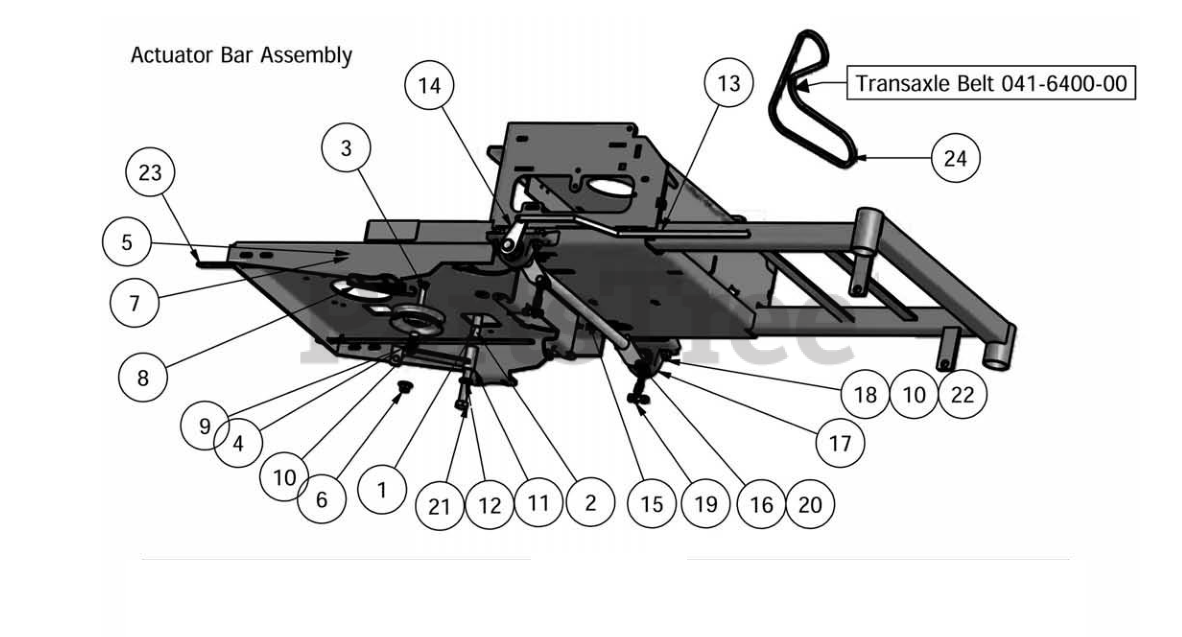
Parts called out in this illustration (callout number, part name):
1	Bronze Bushing
2	Grease Fitting
3	1/2-13 x 3" Bolt
4	1/2" x 1/2" Spacer
5	Spring Tensioner
6	1/2" Flange Lock Nut
7	1/2" Hex Jam Nut
8	Pump Idler Spring
9	4 3/4" Idler Pulley
10	1/2" Lock Washer
11	Pump Idler Bracket
12	5/8" Nylon Washer
13	Height Indicator Bar
14	Height Indicator Lever
15	Actuator Bar
16	3/8" Nylock Nut
17	Pillow Block Bearing
18	1/2" x 1 1/2" Hex Bolt
19	ZT Deck Hanger Assembly
20	3/8" x 1 1/2" Bolt
21	5/8" x 4" Bolt
22	1/2" Nylock Hex Nut
23	Transaxle Neutral Lever
24	Transaxle Pump Belt
